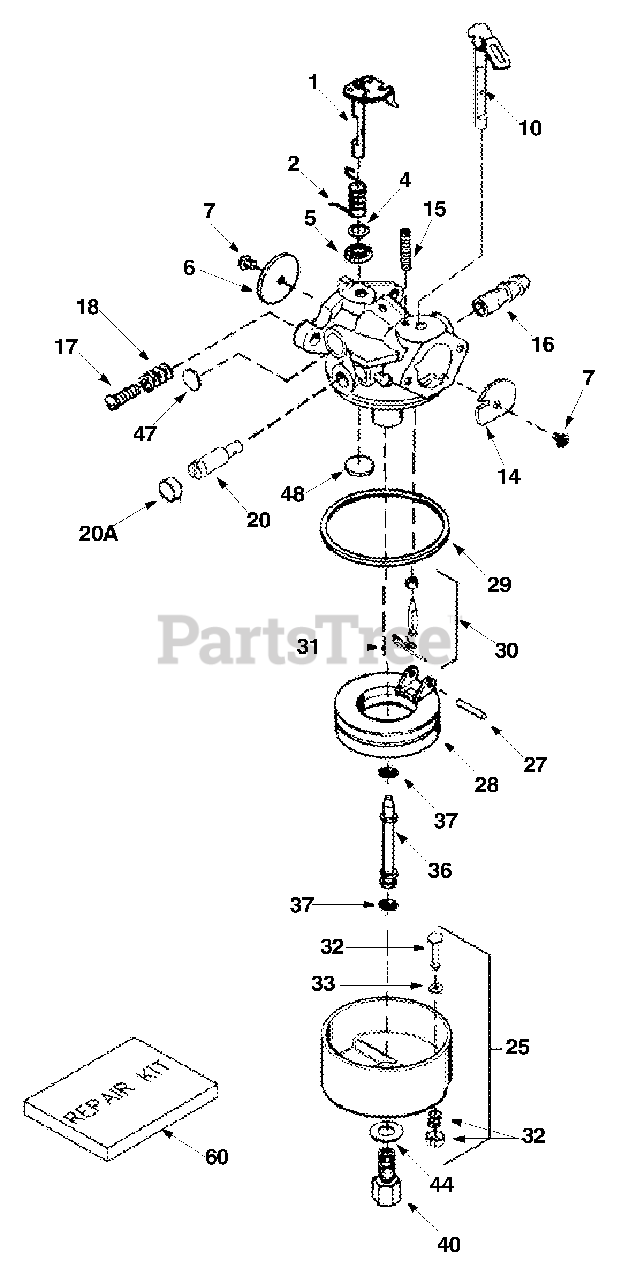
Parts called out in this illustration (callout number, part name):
1	Throttle Shaft & Lever Assembly
2	Throttle Return Spring
4	Dust Seal Washer
5	Dust Seal (Throttle)
6	Throttle Shutter
7	Shutter Screw
10	Choke Shaft & Lever Assembly
14	Choke Shutter
15	Choke Positioning Spring
16	Fuel Fitting
17	Throttle Crack Screw/Idle Speed Screw
18	Tension Spring
20	Idle Restrictor Screw
20A	Idle Restrictor Screw Cap
25	Float Bowl Assembly
27	Float Shaft
28	Float (Plastic)
29	Float Bowl O-Ring
30	Inlet Needle, Seat & Clip
31	Spring Clip
32	Bowl Drain Assembly
33	Drain Plunger Gasket
36	Main Nozzle Tube
37	O-Ring, Main Nozzle Tube
40	High Speed Bowl Nut
44	Bowl Nut Washer
47	Welch Plug, Idle Mixture Well
48	Welch Plug, Atmospheric Vent
60	Repair kit
